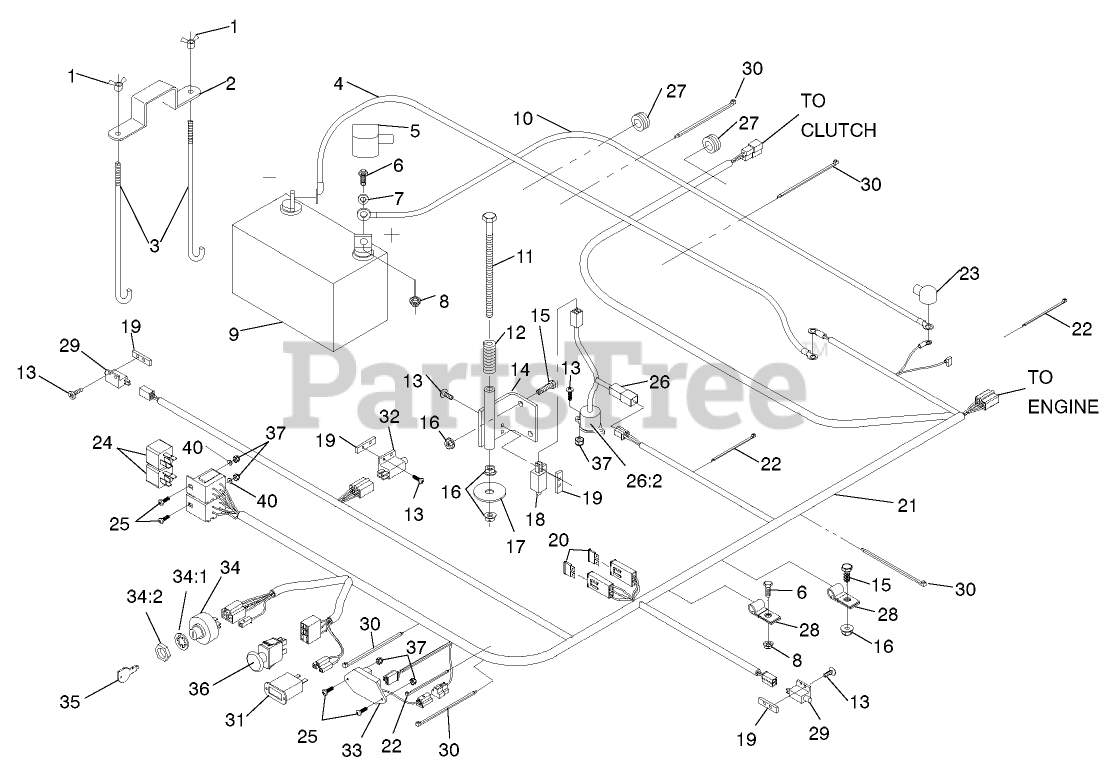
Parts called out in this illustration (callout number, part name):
1	WINGNUT
2	STRAP-HOLDDOWN
3	BOLT-HOLDDOWN
4	CABLE-GROUND, NEGATIVE
5	INSULATOR-BATTERY
6	SCREW-HH
7	WASHER-FLAT
8	NUT-HF
9	BATTERY
10	WIRE-STARTER
11	SCREW-HH
12	SPRING-SWITCH, SEAT
13	SCREW-PPH
14	BRACKET-SWITCH, SEAT
15	SCREW-HH
16	NUT-HF
17	WASHER
18	SWITCH-CLOSED, NORMALLY
19	PLATE-TAPPED
20	FUSE-BLADE TYPE, 20 AMP
21	HARNESS-WIRE
22	TIE-CABLE
23	INSULATOR-SOLENOID
25	BOLT-CARR
26	TILT SWITCH ASM
26:2	DECAL-SWITCH, MERCURY
27	GROMMET
28	CLIP-LOOM
29	SWITCH-OPEN, NORMALLY
30	TIE-PLASTIC
31	METER-HOUR
32	SWITCH
33	MODULE-DELAY, SEAT
34	Key Switch ASM
34:1	WASHER-TOOTH, INTERNAL
34:2	NUT-HH
35	KEY-IGNITION
36	SWITCH-DELTA
37	NUT-LOCK, NI
40	WASHER-FLAT
